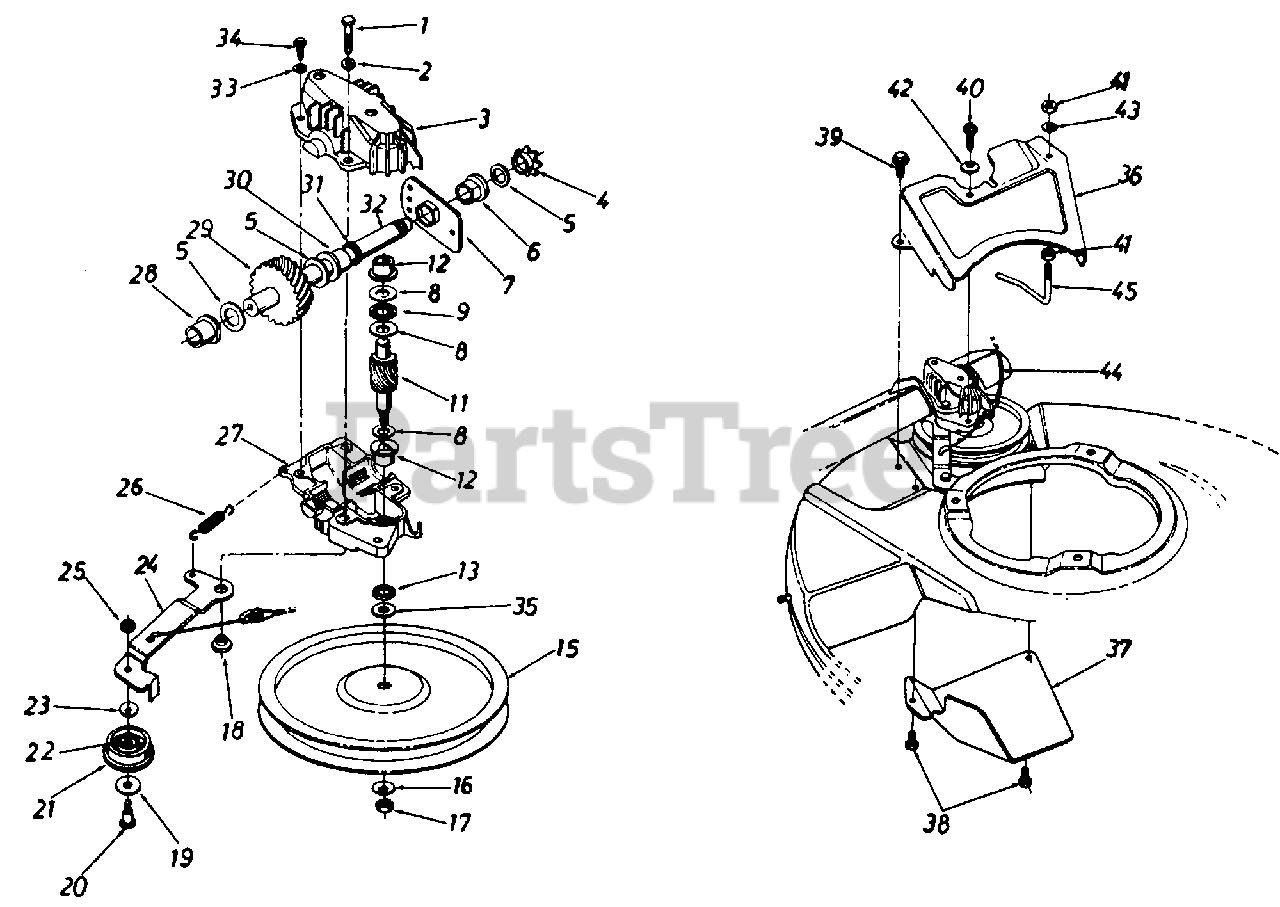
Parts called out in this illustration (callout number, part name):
1	SCREW-HEX
2	L-Wash. 1/4" I.D.
3	HOUSING HALF-UPPER
4	SPROCKET-7T
5	WASHER-FL
6	BEARING-HEX FLANGE
8	WASHER-THRUST.382 X .684
9	BEARING-THRUST
11	SHAFT-PINION 11 T
12	BEARING-FLANGE
13	SEAL-OIL-.375 ID
16	WASHER-SPRING BELL
17	NUT-LH THD-1/4 X 28
18	SPACER-SHLD
19	WASHER-FL .995 X .032
20	SCREW-SHLD
21	PULLEY
22	BEARING-NEEDLE
23	WASHER-SPRING BELL
24	BRACKET ASSY-IDLER
25	NUT-HEX 1/4-28
26	SPRING-EXTENSION
27	HOUSING HALF-LOWER
28	BEARING-FLANGE
29	SHAFT-ASSY W/GEAR
30	BEARING-FLANGE
32	SHAFT-ASSY W/GEAR
33	WASHER-LOCK-#10
34	SCREW-HEX WASH HD TAP
35	WASHER-HEX
39	SCREW-HEX WASH SF TAPP
40	SCREW-HEX B-TAP 1/4-.62
41	NUT-HEX 1/4-20
42	WASHER-SPRING BELL
43	LOCK WASHER 1/4 DIA
44	CABLE-CLUTCH
45	GUARD-BELT
